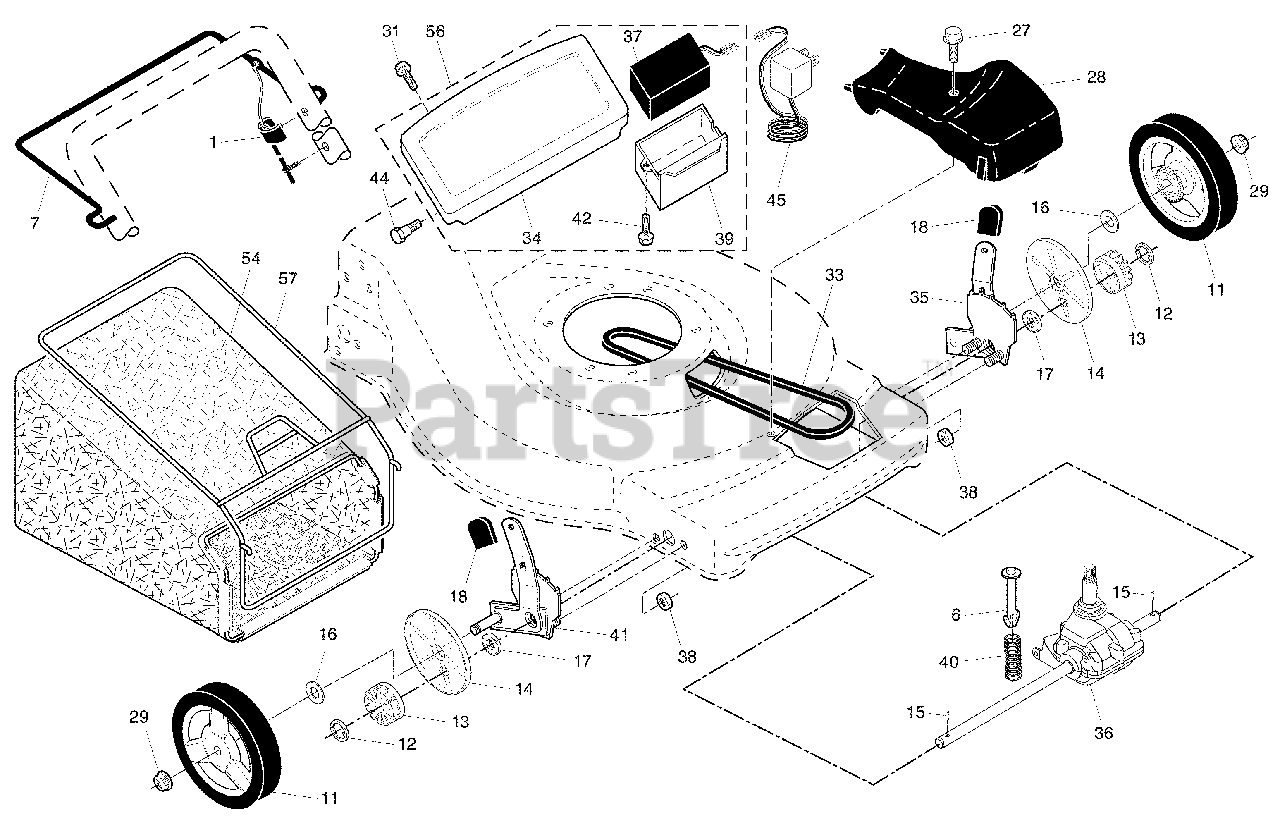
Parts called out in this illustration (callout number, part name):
1	Drive Control Cable
6	Retainer, Spring
7	Bar, Drive Control
11	Wheel & Tire Assembly
13	Gear, Pinion
14	Dust Cover
15	Pawl, Drive
16	Washer, Flat 3/8
17	Ball Bearing
18	Selector Knob
27	Pan Head Tapping Screw #10-24 x 2-3/4
28	Drive Cover
29	Locknut, Hex
31	Screw, Torx Pan Head #20
33	V-Belt
35	Kit, Wheel Adjuster, LH
36	Gear Case Assembly, Complete
37	Battery
38	Locknut, Hex 1/4-20
39	Box, Battery
41	Kit, Wheel Adjuster, RH
42	Screw, Hex Head #13 x 1/2
44	Screw, Shoulder, Hex Head #10-28 x 5/8
45	Charger, Battery
54	Grassbag Assembly
56	Trimplate / Battery / Battery Box Assembly
57	Frame, Grassbag
